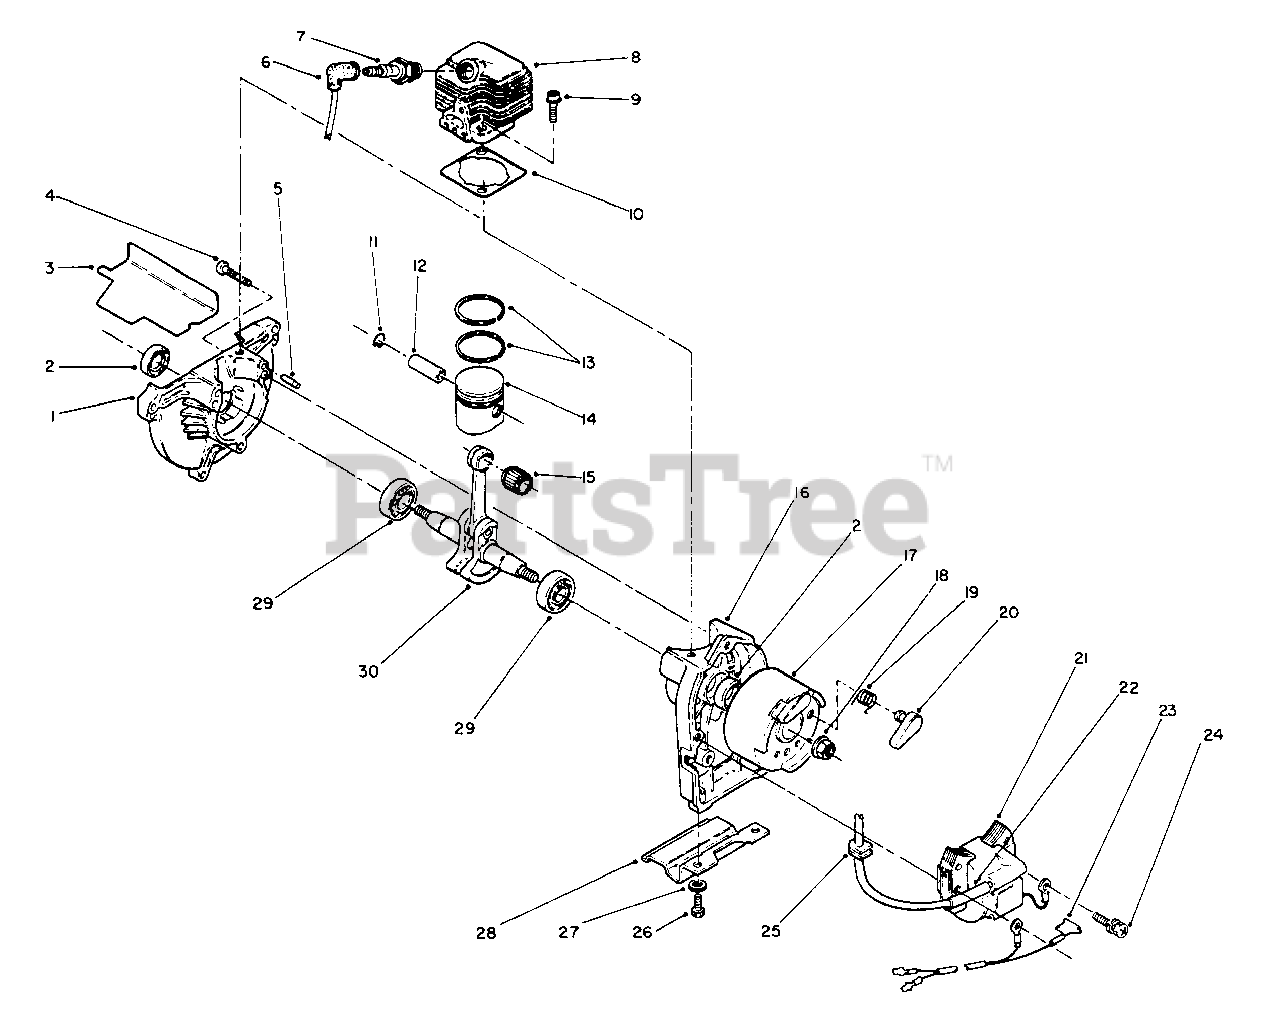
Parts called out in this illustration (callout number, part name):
1	Case-Drive
2	Seal-Oil
3	Gasket-Baffle
4	Screw-Pan Hd.
5	Pin-Dowel
6	Boot-Plug
7	Plug-Spark
8	Cylinder Head
9	Bolt-Cylinder Head
10	Gasket-Cylinder Head
11	Clip-Piston Pin
12	Pin-Piston
13	Set-Piston Ring
14	Piston Ass'y (Incl. Ref. #12)
15	Bearing-Needle
16	Case-Starter
17	Flywheel (Incl. Ref. #19 & 20)
18	Nut-Conical
19	Spring-Return
21	Coil-Ignition
23	Wire Lead Assembly
24	Bolt/Washer
27	Washer-Lock
29	Bearing-Main
30	Crankshaft Assembly
